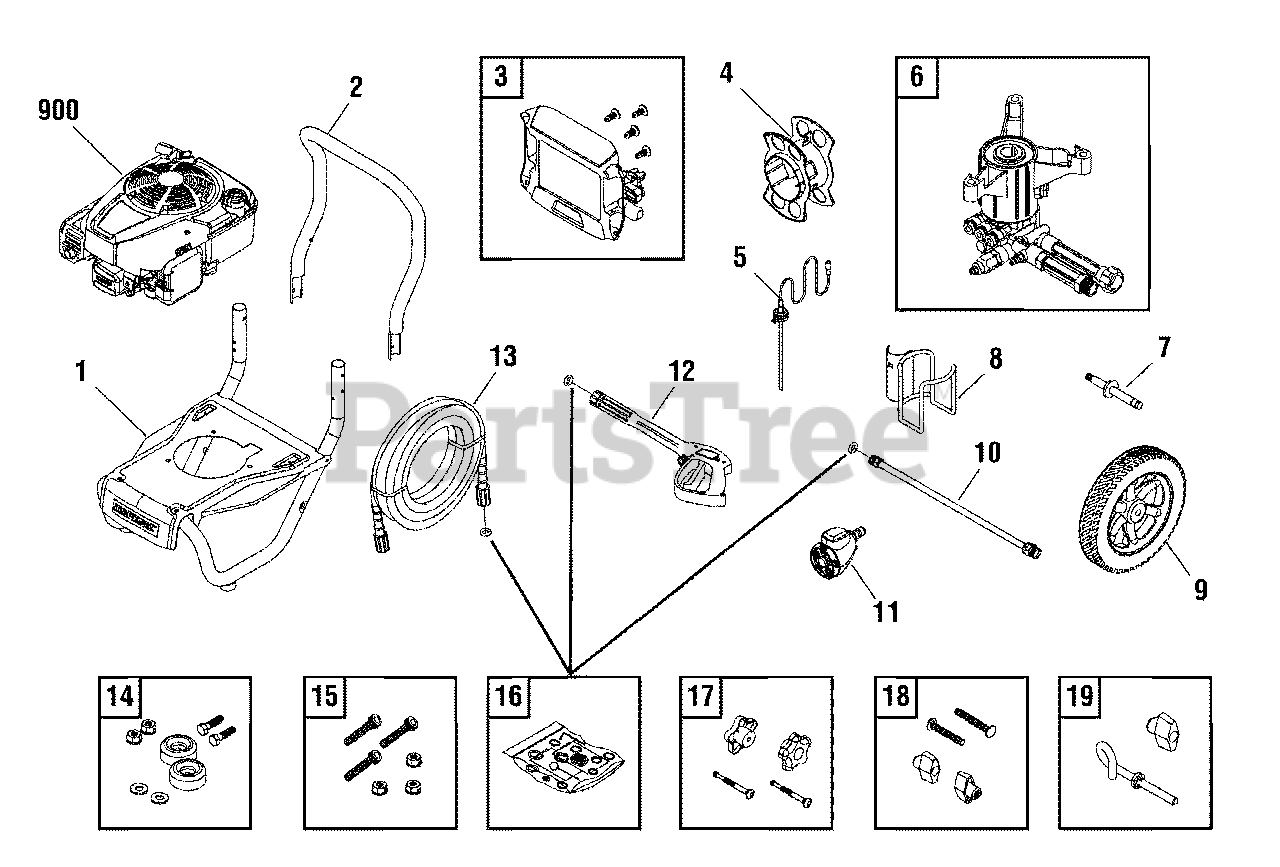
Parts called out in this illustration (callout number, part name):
1	BASE
7	AXLE
10	EXTENSION, QC
11	NOZZLE, QC
12	GUN
13	HOSE
14	MOUNT, Vibration
15	KIT, Hardware, Pump Mounting
16	KIT, O-Ring
